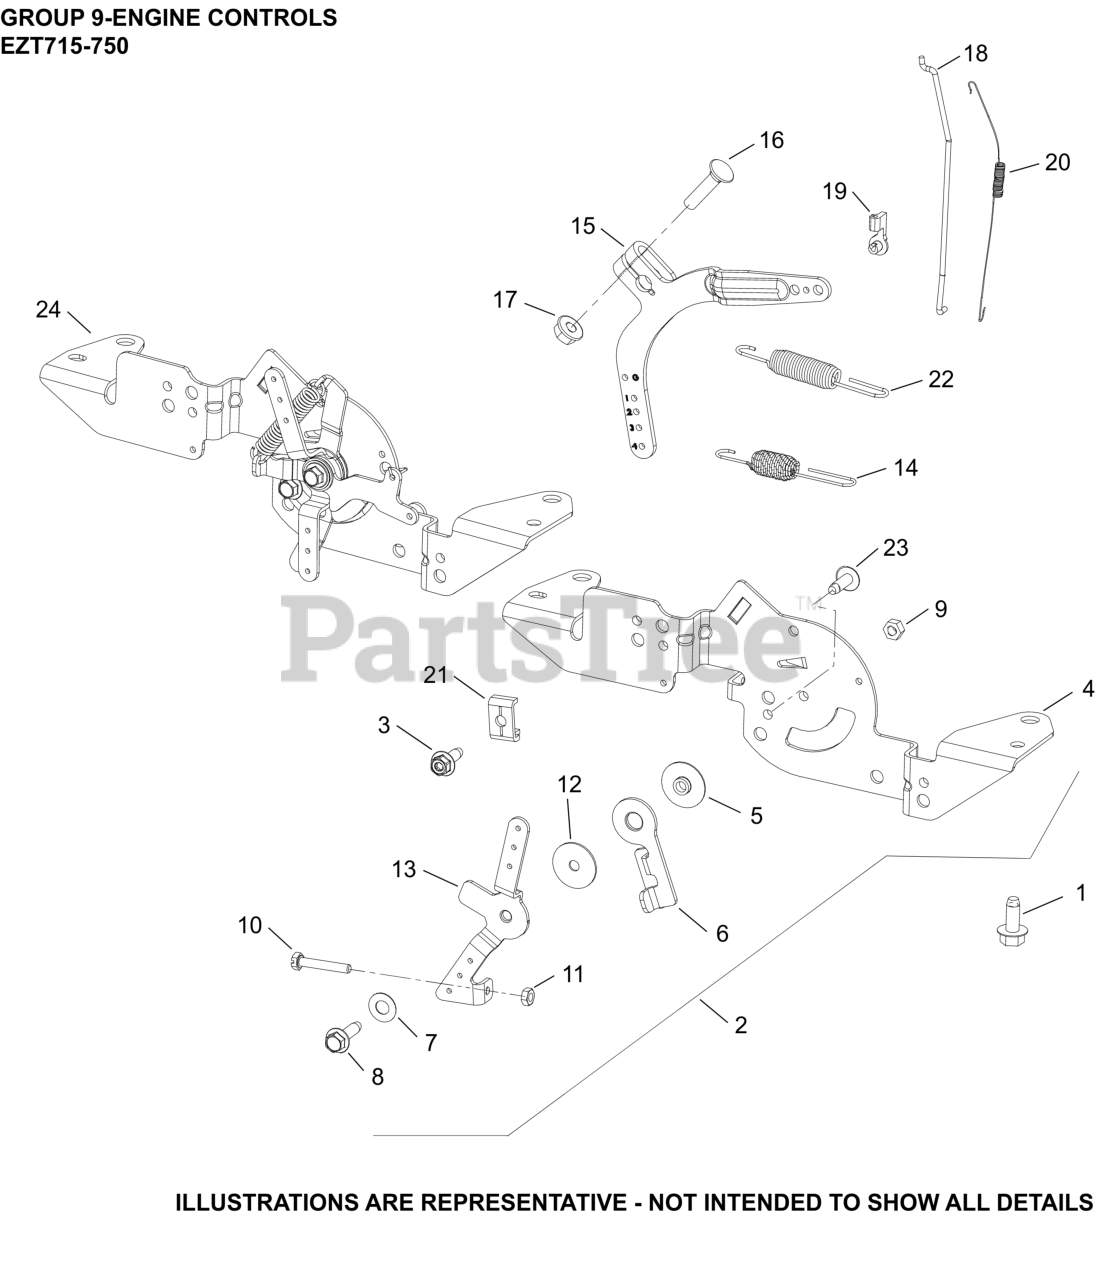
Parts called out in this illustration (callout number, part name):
1	SCREW, THREAD FORMING
3	SCREW, THREAD FORMING
4	BRACKET, SPEED CONTROL
5	SPACER, CONTROL ASSEMBLY
6	LEVER, THROTTLE ACTUATOR
7	WASHER, SPRING 1/4"
8	SCREW, THD FRM-USE 25 086 473-S
9	NUT, LOCK M5X.8
10	SCREW, SLT HD CAP M4X0.7X25
11	NUT, M4X0.7
12	WASHER, FLAT 5 MM
13	LEVER, THROTTLE CONTROL
15	LEVER, GOVERNOR - (#2409069S)
16	BOLT, RD HD SQ NECK M6X1.0X25
17	NUT, FLG M6X1.0
18	LINKAGE, THROTTLE
19	BUSHING, THROTTLE LINKAGE
20	SPRING, LINKAGE
21	CLAMP, CABLE CABLE
22	SPRING, GOVERNOR (CLEAR)
23	SCREW, THREAD FORMING
25	SPRING, CHOKE RETURN
26	LEVER, CHOKE
27	LEVER, GOVERNOR ASSEMBLY
28	WASHER, FLAT 5.5 MM
29	CONTROL ASSEMBLY, DUAL WIRE
